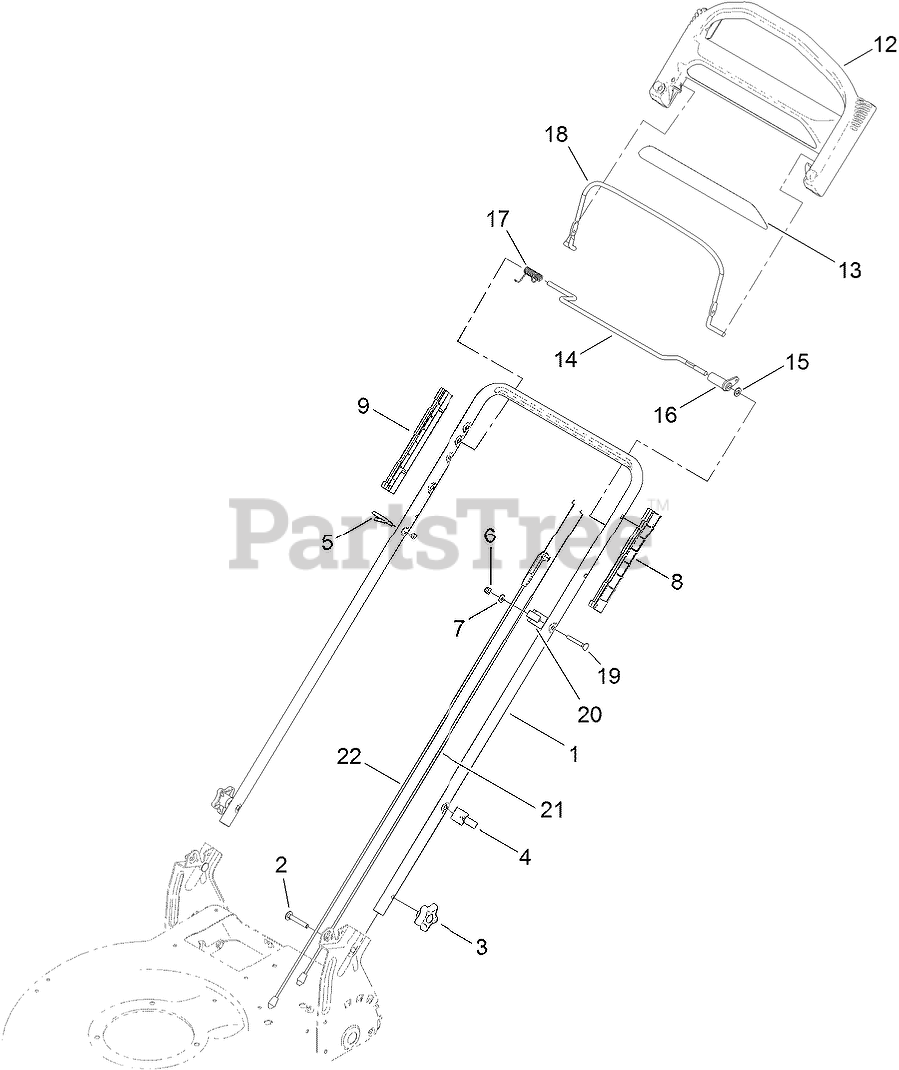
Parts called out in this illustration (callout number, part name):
2	Screw-CARR
3	KNOB-HANDLE
4	GUIDE-CABLE
5	GUIDE-ROPE
6	NUT-LOCK, NI
7	WASHER-FLAT
8	GUIDE-LH
9	GUIDE-RH
12	HANDLE-CONTROL
13	DECAL-HANDLE
14	BAR-CONTROL, TRACTION
15	WASHER-PLAIN
16	LEVER-TRACTION
17	Spring-Torsion
18	Bail-Brake
19	SCREW
20	ANCHOR-CABLE
21	CABLE-TRACTION
22	CABLE-BRAKE
